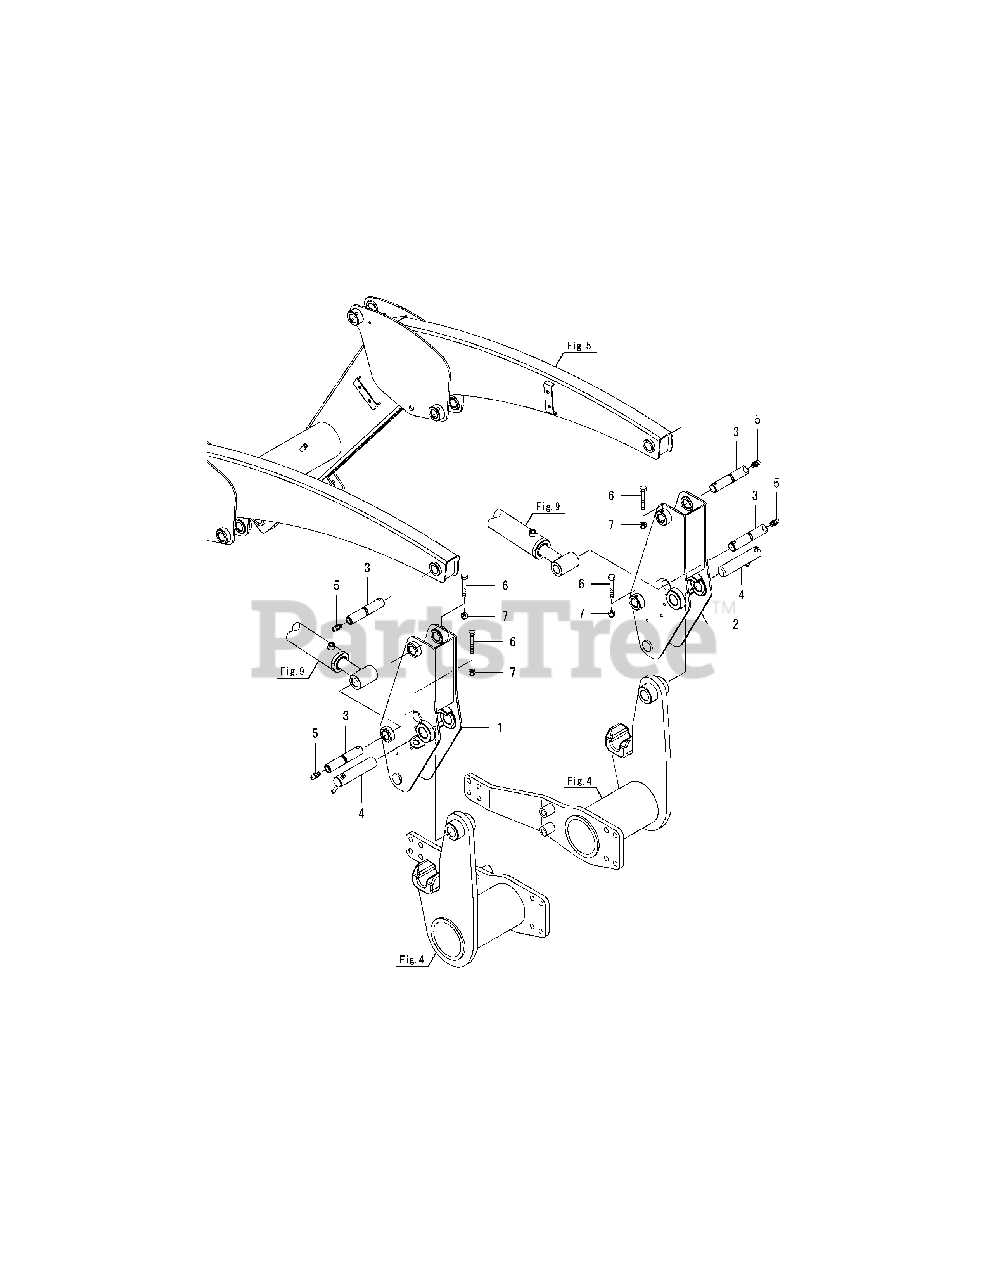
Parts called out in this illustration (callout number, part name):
1	SUPPORT M ASSY, L
2	SUPPORT M ASSY, R
5	NIPPLE M6F, GREASE
6	BOLT M 8X 60 PLATED
